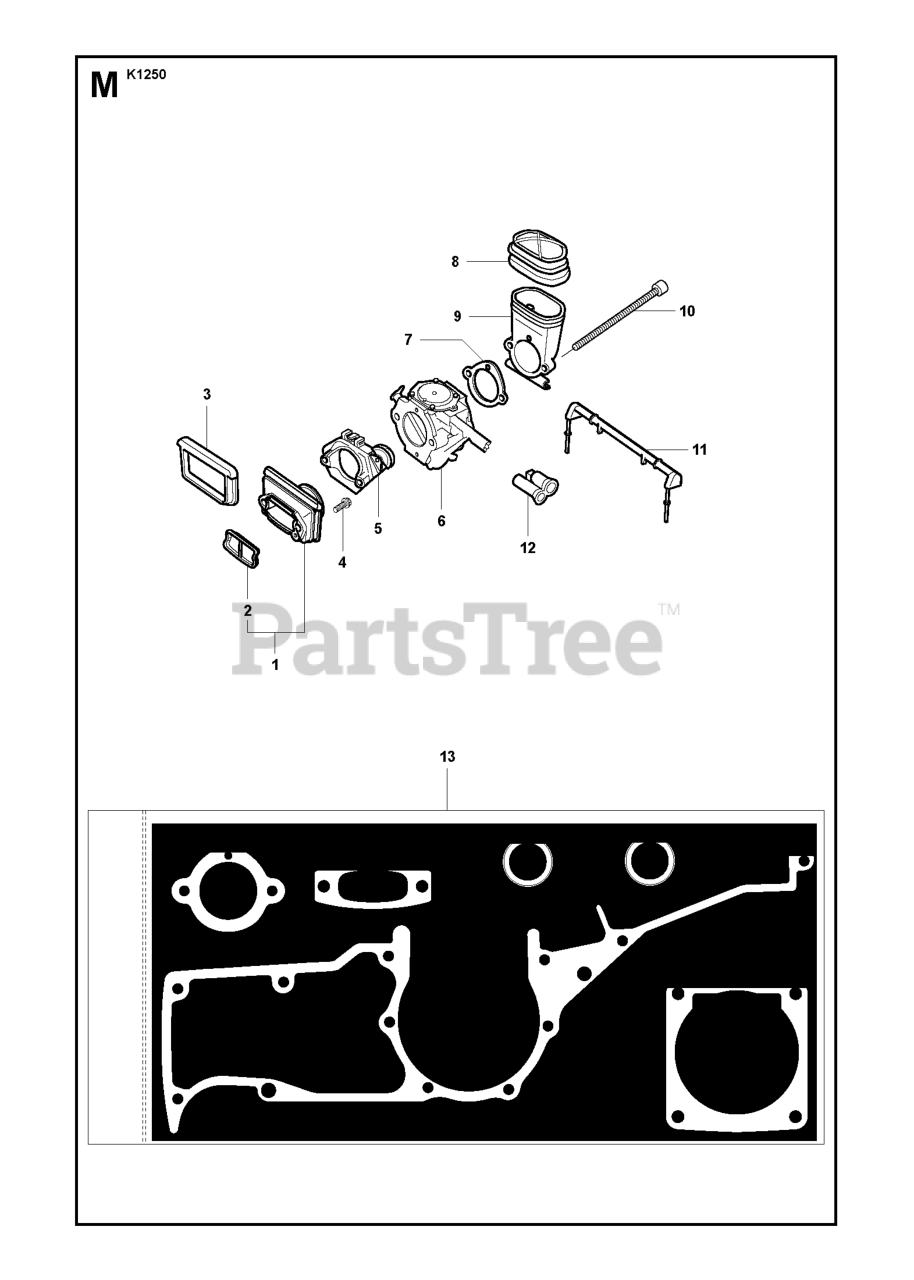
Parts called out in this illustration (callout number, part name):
1	INTAKE PIPE
6	CARBURETOR WGA WALBRO
7	RP GASKET
13	GASKET SET
14	RP GASKET
15	SEALING RING
16	CRANKCASE GASKET
